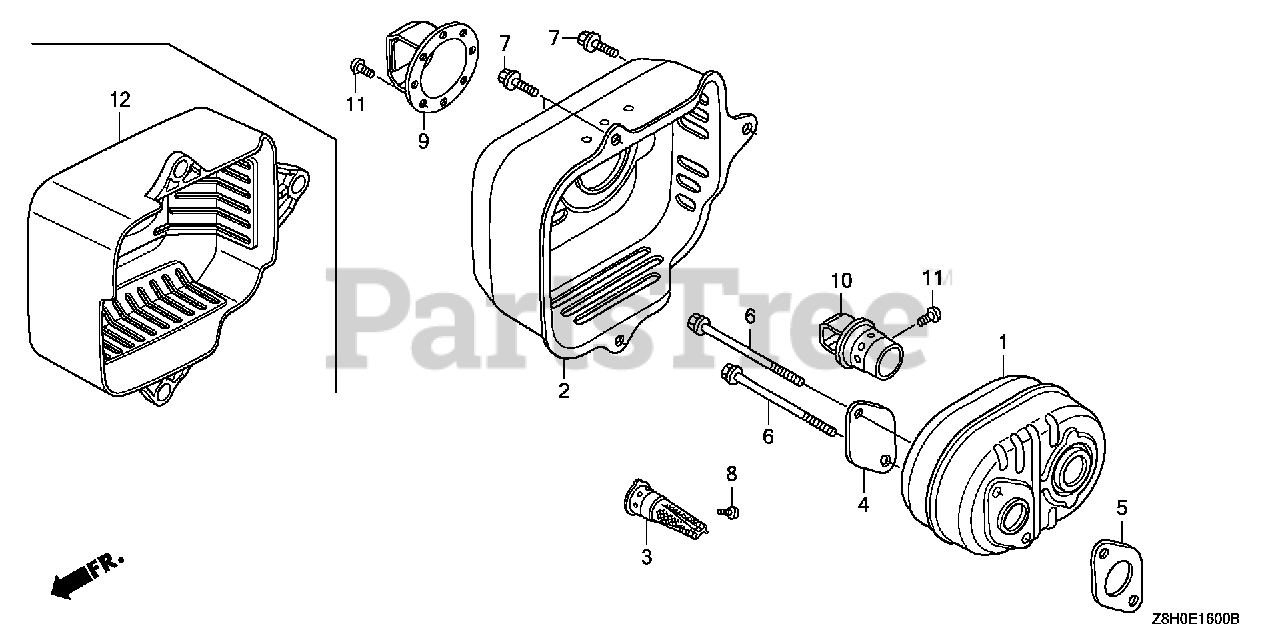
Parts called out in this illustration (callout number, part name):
1	MUFFLER
2	PROTECTOR, MUFFLER
5	GASKET, MUFFLER
6	BOLT, FLANGE (6X79) (CT200)
7	BOLT, FLANGE (6X12) (CT200)
